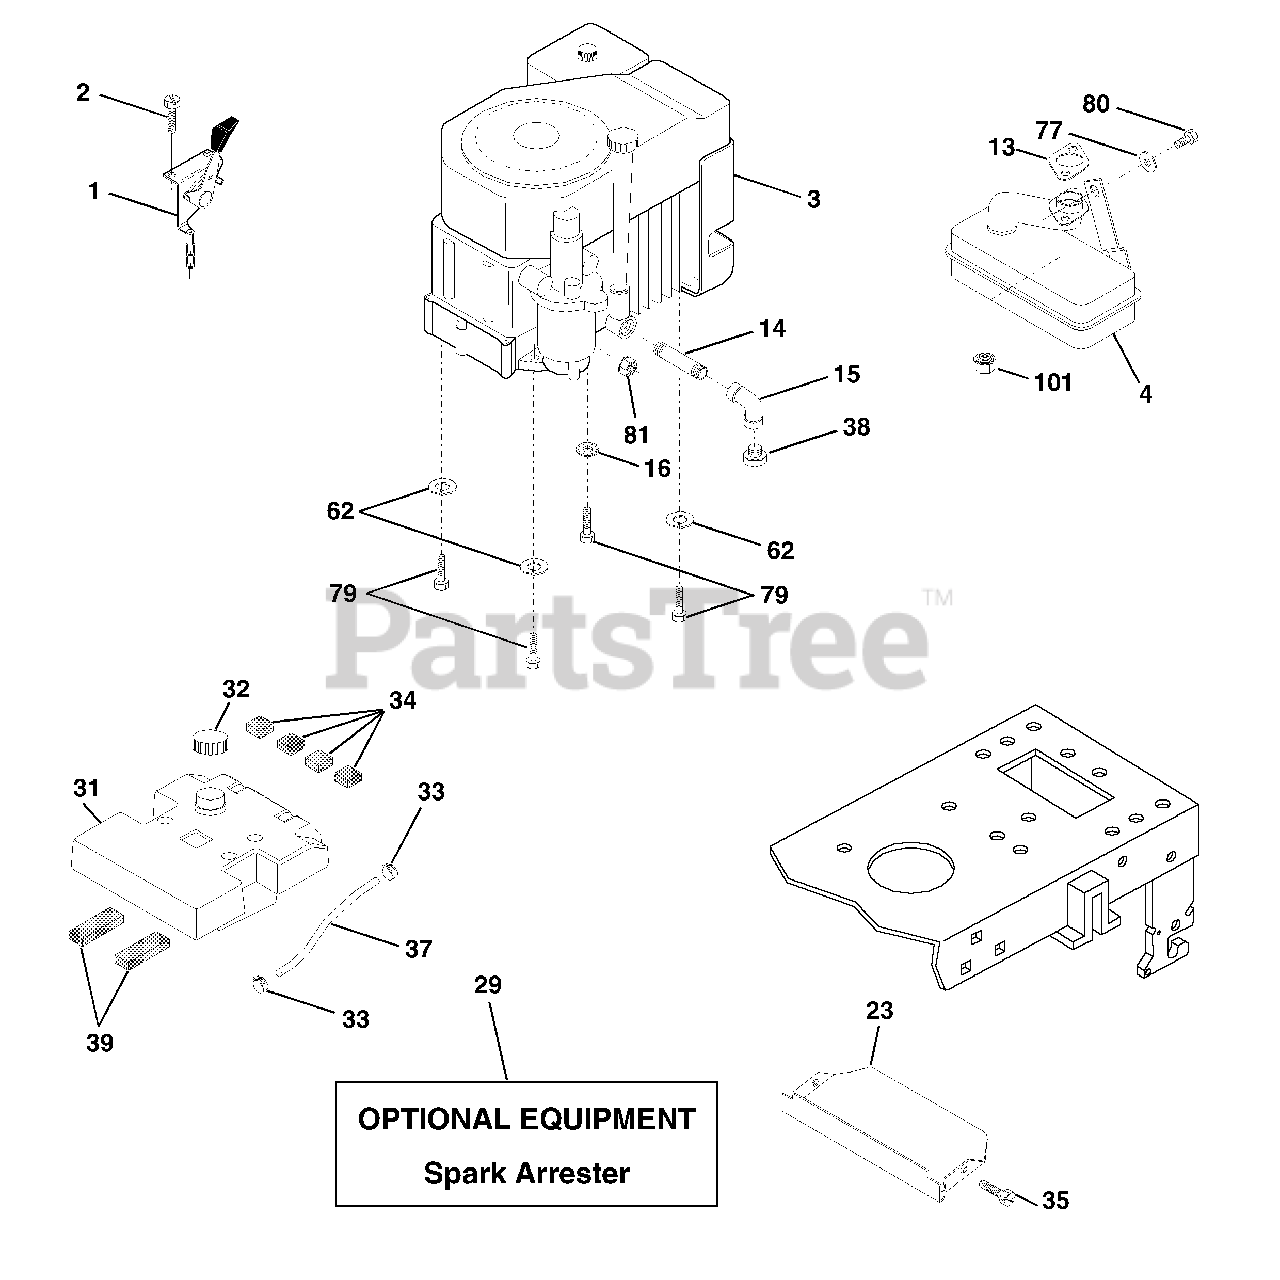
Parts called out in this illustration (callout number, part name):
1	Control Th/ch 27. LH. Flag Dom.
2	Screw Hex Thd Cut 1/4-20x5/8 T
4	Muffler Kohler Single w/Port
13	Gasket Kohler CV13-CV16.5
14	Nipple Pipe 3/8 Npt X 3-1/2
15	Elbow Std 90 Degree 3/8-18 Npt
16	Washer Lock Ext Tooth 5/16
23	Shield BRN/DBR Guard
29	Kit Spark Arrestor (Flat Scrn)
31	Tank Fuel 3.5 STLT W/O Sensor
32	Cap Asm Fuel W/sym Vented
33	Clamp Hose Black
34	Pad Spacer
35	Screw
37	Line Fuel 7.5"
38	Plug Oil Drain
39	Pad Idler 1.75 x .75 x .06
62	Washer Lock Hvy Hlcl Spr 5/16
77	Washer 5/16 x 3/4 x 16 Ga.
79	Bolt Hex
80	Bolt Hex Hd. 5/16-18unc x 1/2
81	Nut Flange 1/4-20 Starter Nut
101	Nut Flange M8-1.25 Non-LK
